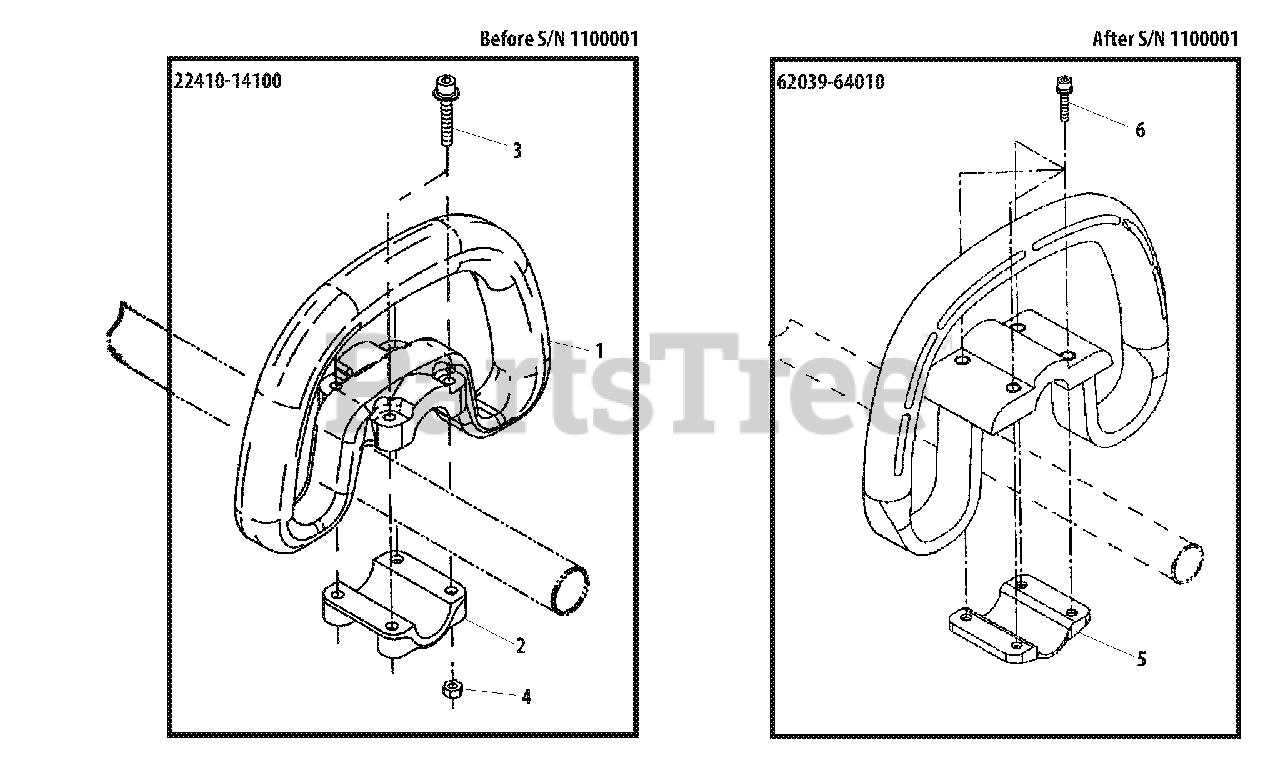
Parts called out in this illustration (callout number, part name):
1	HANDLE, FRONT
2	BRACKET, MOUNTING
4	NUT M5
5	BRACKET, MOUNTING
6	BOLT M5×25
A	FRONT HANDLE ASSY
B	HANDLE ASSY
